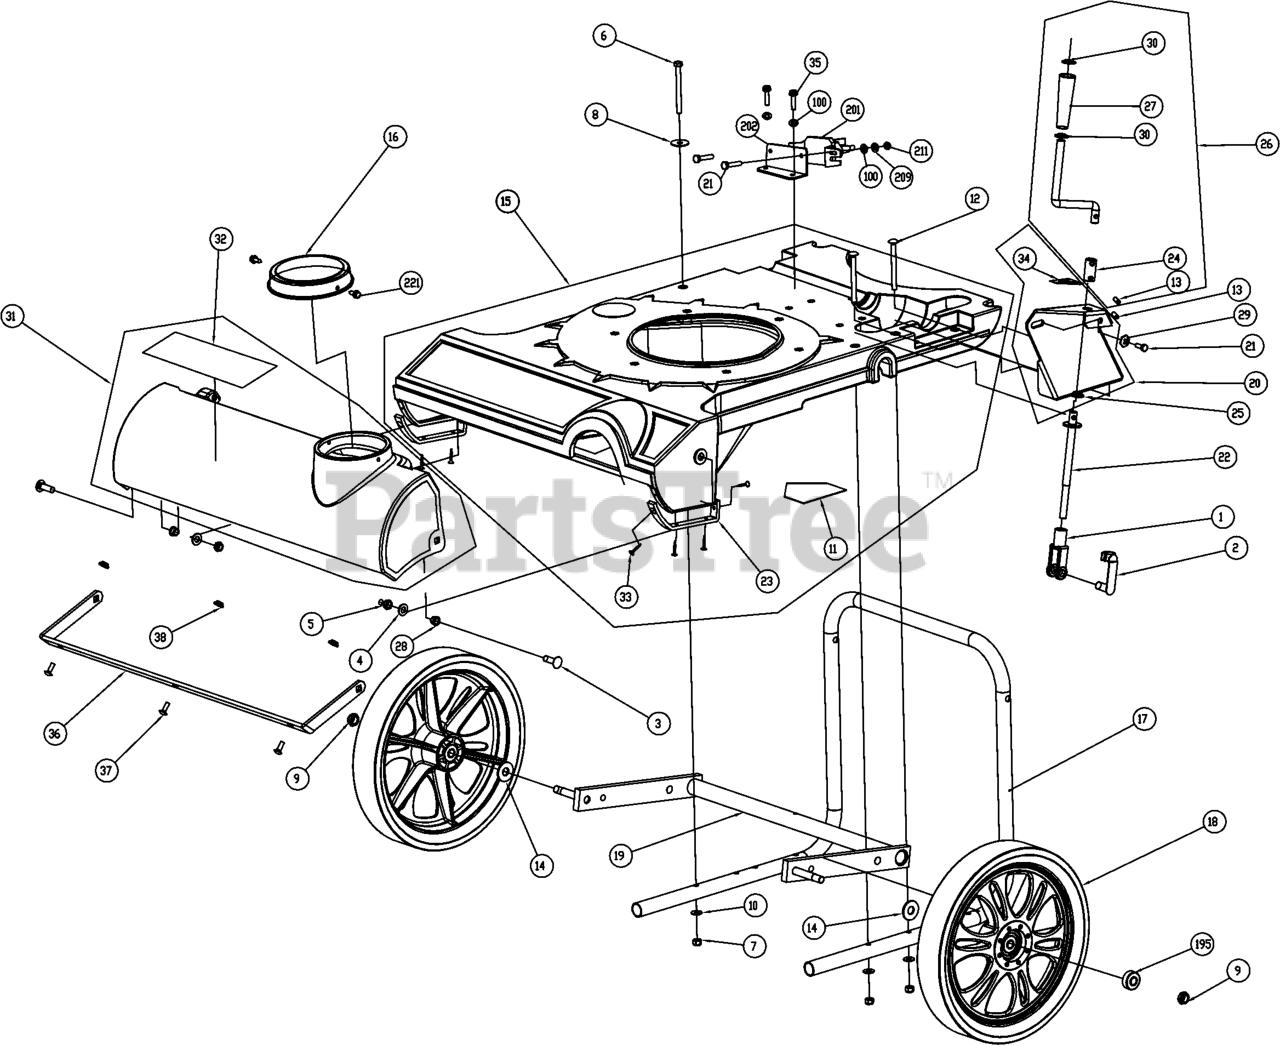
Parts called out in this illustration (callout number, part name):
1	YOKE 1/2"-20
2	PIN YOKE 1/2"
3	SCREWCAP BUTTON HEAD, 3/8-16 X 1 1/4" PL
4	WASHER 3/8"SAE 13/32"X13/16"X1/16"
5	NUT LOCK 3/8-16 LT WT THIN ZP
6	SCREWCAP 5/16"-18X3 1/2" HCS ZP
7	NUT LOCK 5/16"-18 HEX Z/P
8	WASHER FLAT FENDER 5/16
9	NUT LOCK 1/2"-13 NYLON INSERT
10	WASHER 1/4" FLAT Z/P
11	LABEL WARNING OPEI
12	BOLT CARRIAGE 5/16"-18 X 3 1/2" ZP
13	PIN ROLL 1/4" X 1"
14	WASHER 1/2" SAE Z/P
15	NOZZLE MV VAC ASSEMBLY
16	PLUG HOSE 5" VAC
17	HANDLE LOWER BRACE MV
18	WHEEL AND TIRE 14" SMOOTH
19	AXLE FRONT WA VAC
20	BRACKET HGT ADJ WA WA/LABEL MV VAC
21	SCREWCAP 1/4"-20X3/4" HCS ZP
22	LINK HGT ADJ SP VAC
23	BRACKET NOZZLE WEAR GUARD VAC
24	ROD CONNECT HGT ADJ
25	BUSHING 0.5 ID 0.625 OD X 0.25
26	ROD HANDLE CRANK ASSEMBLY
27	HANDLE CRANK
28	BUSHING 3/8 ID X 1/2 OD X 3/8
29	WASHER LOCK 1/4" TWISTED TOOTH
30	INTERNAL TOOTH WASHER BRASS
31	NOZZLE COVER MV VAC ASSY
32	LABEL BADGING MV
33	SCREW SHEETROCK 1" LONG
34	LABEL HGT ADJ MV VAC
35	SCREW SM 1/4"X3/4" TYPE A HX WF
36	BRACKET NOZZLE COVER REINFORCE
37	BOLT CARRIAGE 1/4" X 3/4"
38	NUT WHIZ 1/4"-20 WASH FACE
100	WASHER 1/4"SAE9/32"X5/8"X1/16"
195	BEARING 1/2 ID
201	SOLENOID ELECTRIC START
202	BRACKET SOLONOID MOUNT
209	WASHER LOCK 1/4" EXTERNAL TOOTH
211	NUT 1/4"-20 FIN HEX Z/P
221	SCREW PLASTITE 1/4-10 X 3/4 HWH ZP
